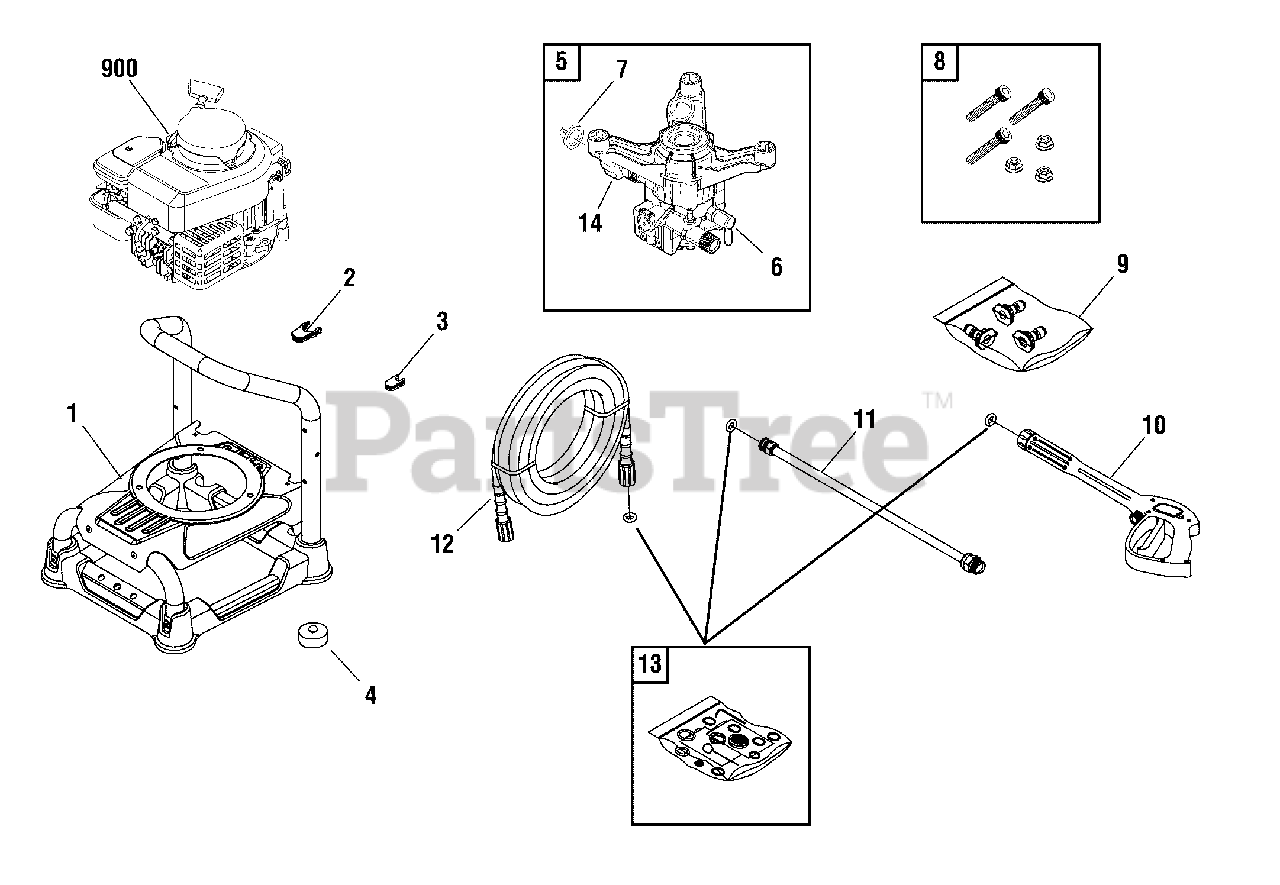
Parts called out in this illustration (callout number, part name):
4	MOUNT, Vibration
5	PUMP
6	VALVE-THERMAL RELIEF
7	FILTER-GARDEN HOSE
8	KIT, Hardware, Pump Mounting
9	KIT, QC Nozzles
10	GUN
11	EXTENSION, QC
12	HOSE
13	KIT, 0-Ring
14	ADAPTER-GARDEN HOSE
